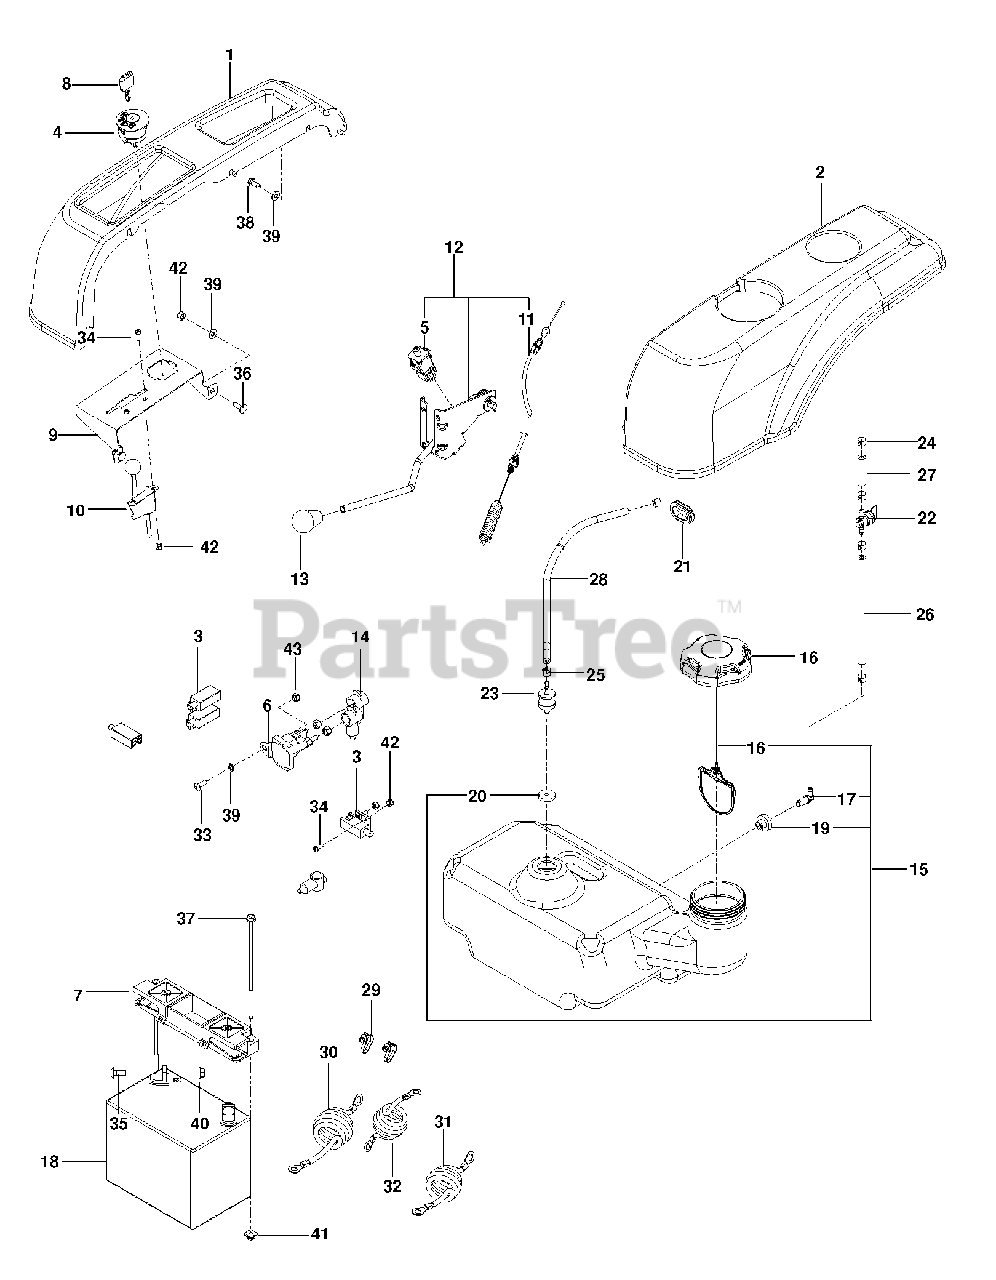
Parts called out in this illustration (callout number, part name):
1	FENDER, RZ 30/38 RT
2	FENDER, RZ 30/38 LT
3	SWITCH INTERLOCKT
4	RP IGNITION SWITCH
5	SWITCH INTERLOOK PUSH-IN
6	SOLENOID.W/BRASS.PLUNGER
7	BATTERY HOLD DOWN
8	KEY MLD GEN DELTA
9	MOUNT, CONTROLS, BLK
10	CABLE.THROTTLE.20"
11	CABLE.CLUTCH.38".SERVICE
12	ASM, CLUTCH ENGAGE W/CABLE
13	KNOB - SHIFT
14	TERMINAL COVER-SM
15	FUEL TANK ASM SMALL
16	CAP, FUEL
17	STEM, FUEL TANK
18	BATTERY, 12 V 330 AMP
19	RUBBER GROMMET
20	GROMMET, CHECK VALVE
21	RUBBER GROMMET
22	FUEL VALVE
23	VALVE.FUEL.CHECK
24	HOSE CLAMP
25	CLAMP, HOSE
26	HOSE 1/4 X 8
27	HOSE 1/4 X 2"
28	HOSE, FUEL, 3/16" X 20"
29	TIE WRAP, 8-3/8", W/CLIP
30	POST.CABLE LONG
31	CABLE POSITIVE, LONG
32	BATTERY CABLE, NEGATIVE
33	HCS 1/4C X 3/4 HCS
34	SCREW #10-24 X 5/8
35	BOLT 5/16-18 X3/4 ZN/YEL GR 5
36	BOLT
37	BOLT 1/4-20 X 7.5
38	SCREW 1/4 X 5/8
40	5/16-18 NYLOC FLANGE NUT
41	PUSH NUT-NYLON
42	NUT 10-24 NYLOC
43	LOCKNUT.NYLOC.1/4-20
